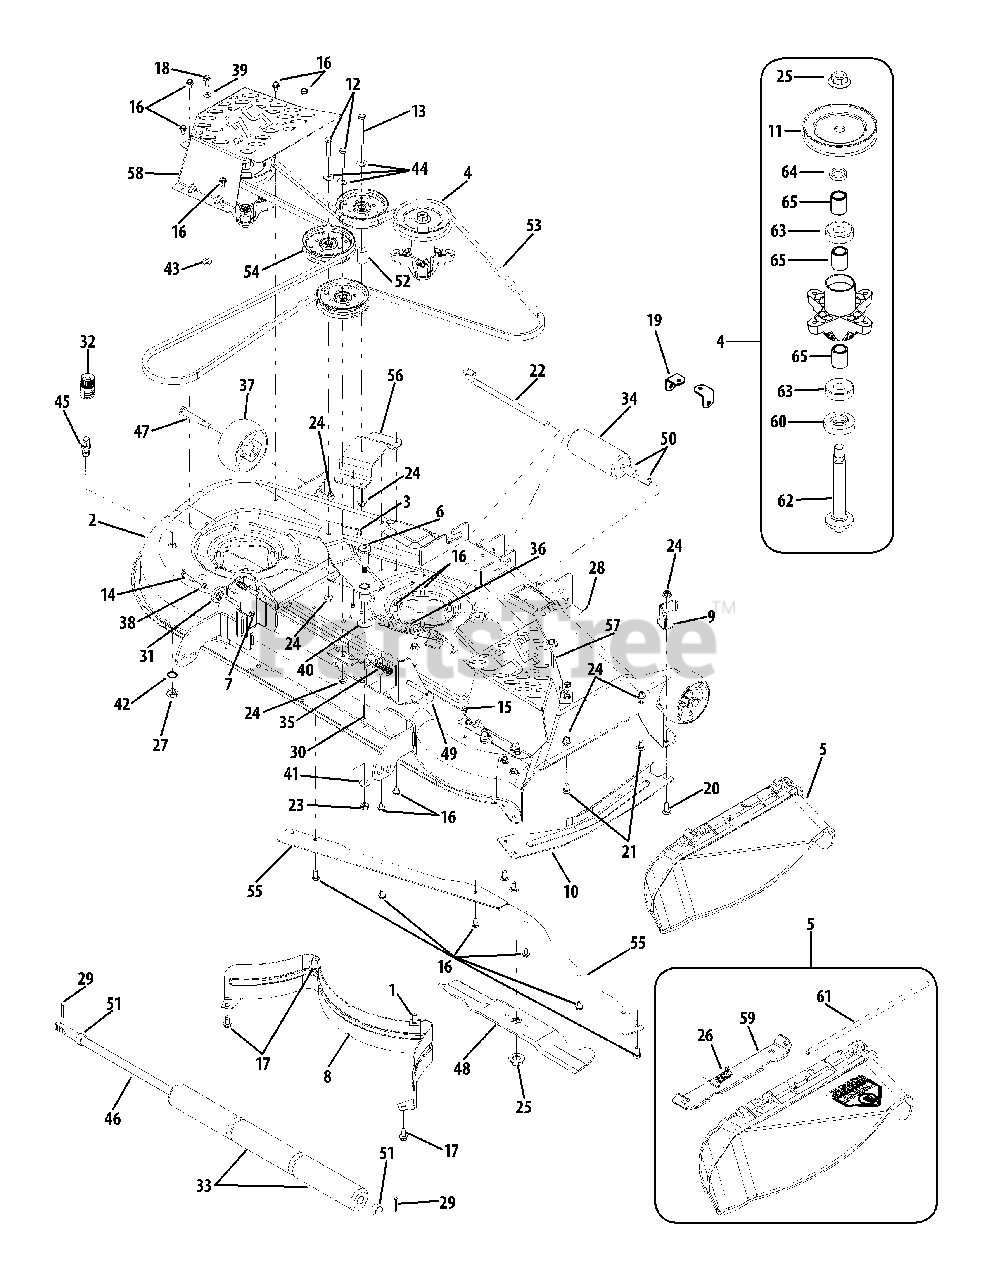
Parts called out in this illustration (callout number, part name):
1	Carriage Screw, 3/8-16 x 1.00
2	Deck Housing
3	Idler Assembly
4	Spindle Assembly
5	Discharge Chute Assembly
6	Shoulder Bolt Assembly
7	Deck Hanger Bracket
9	Stop Bracket
10	Finger Guard
11	V-Type Pulley, 5.39
12	Hex Cap Screw, 3/8-16 x 1.75
13	Hex Cap Screw, 3/8-16 x 3.0
14	Hex Cap Screw, 5/16-18 x 1.25
15	Hex Washer Screw, 1/4-20 x .5
16	Hex Washer Screw, 5/16-18 x .750
17	Hex Washer Screw, 3/8-16 x .75
18	Hex Washer Screw, 5/16-18 x .875
19	Frame Support Bracket
20	Hex Screw, 3/8-16 x 1.00
21	Carriage Screw, 3/8-16 x .75
22	Roller Pin, .5 x 10.06
23	Hex Lock Nut, 7/16-14
24	Hex Insert Flange Lock Nut, 3/8-16
25	Hex Flange Nut, 5/8-18
26	Torsion Spring, .44 ID x 2.00
27	Hex Nut, M16-1.5
28	Cotter Pin, 3/32 x 1.0
29	Cotter Pin, 5/32 x 1.25
30	Cotter Pin, 1/8 x 1.25
31	Deck Adjustment Gear
32	Water Nozzle Adapter
33	Deck Roller, 7.895
34	Front Roller
35	Compression Spring, .535 x 1.751
36	Extension Spring, .94 x .04609
37	Deck Ball Wheel, 5.0
38	Lock Washer, 5/16
39	Flat Washer, .344 x .688 x .065
40	Flat Washer, .442 x 1.39 x .06
41	Bell Washer, .45 x 1.0 x .062
42	Lock Washer
43	Flat Washer, .407 x .812 x .135
44	Flat Washer, .38 x .93 x .110
45	Deck Wash Nozzle
46	Shaft, .75 x 26.893
47	Shoulder Screw, .5 x 2.5 x 3/8-16
48	Blade, 18.5
49	Deck Hanger Rod
50	Spacer, .55 x .75 x 1.125
51	Spacer, .82 x 1.0 x.53
52	Spacer, .38 x .9 x 1.313
54	Idler Pulley, 4.25 Dia
55	Deck Skirt
56	Stationary Idler Bracket
57	Belt Cover, RH
58	Belt Cover, LH
59	Chute Mounting Bracket
60	Spacer, .79 x 1.82 x .55
61	Hinge Pin
62	Spindle Shaft, 6.95
63	Ball Bearing
64	Spacer, .79 x 1.25 x .175
65	Spacer, .80 x 1.10 x 1.32
